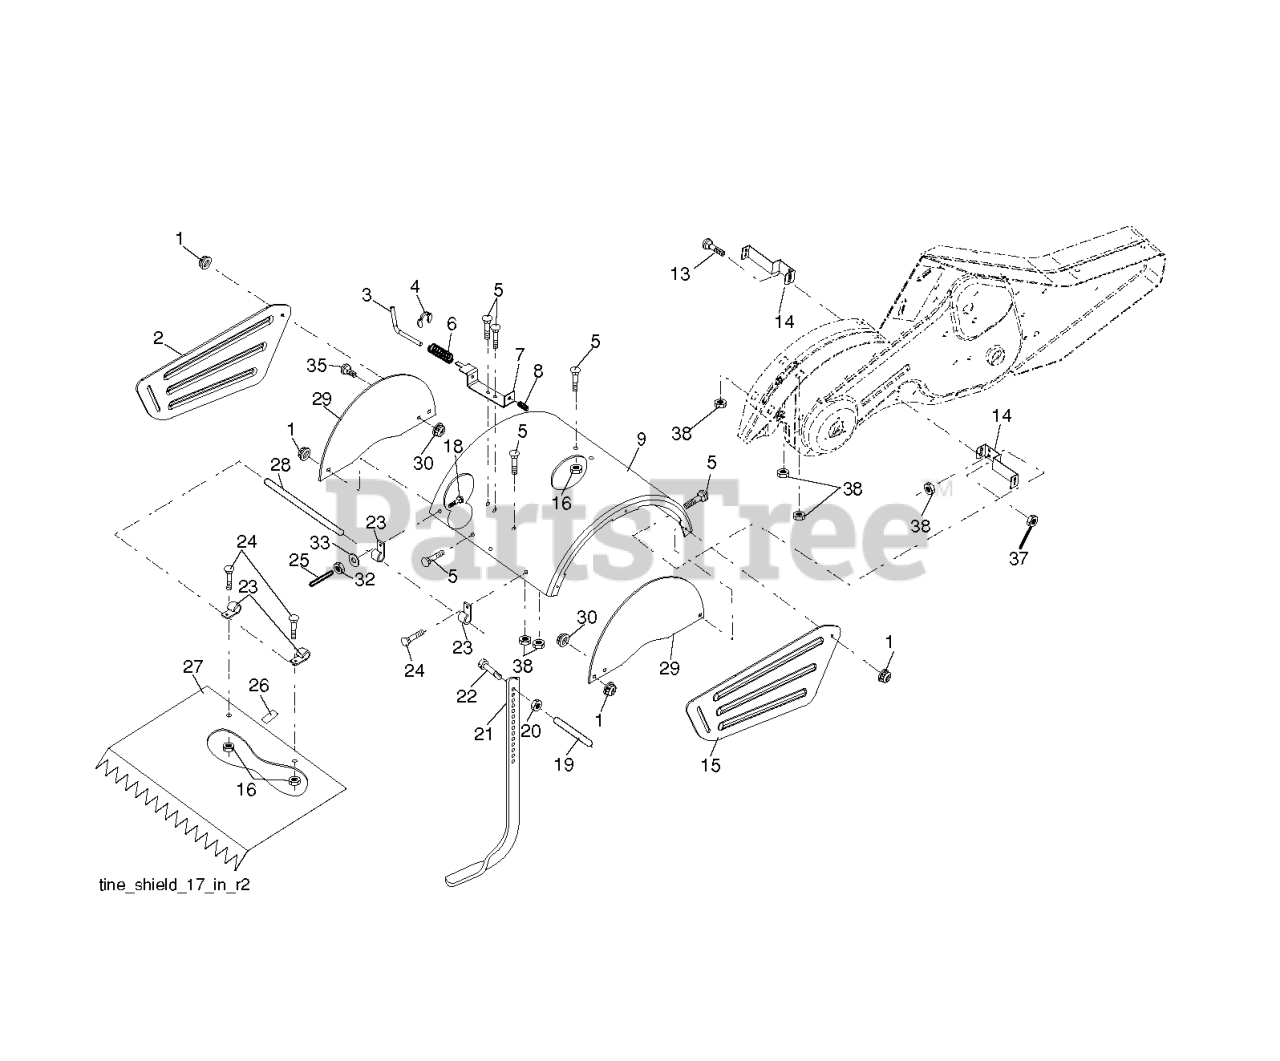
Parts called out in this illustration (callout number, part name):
1	NUT LOCK HEX FLANGE 5/16-18
2	SHIELD
3	STAKE PIN TI
4	RING, KLIP
5	BOLT, RDHD SQNK 5/16-18 X 3/4
7	BRACKET.LATCH.STAKE.3.20.BLACK
8	SPRING CRT
9	SHIELD
13	BOLT.CARRIAGE.5/16-18
14	BRACKET.TINE.SHIELD.TILLER.BLA
15	SIDE SHIELD RH
16	NUT T
20	NUT.HEX.3/8-16UNC
21	STAKE.DEPTH.16.CRT.BLACK
22	BOLT.375-16
25	VINYL CAP TI
26	PAD IDLER TI
27	SHIELD LEVELING
28	PIN.HINGE.TILLER
29	SHIELD.ASM.SIDE.ORANGE.(OLD)
30	LOCKNUT-FLANGE 5/16-18
32	NUT
33	LOCKWASHER
35	BOLT.CARR.5/16-18X5/8.SHORT
37	NUT.71038.31-18.HEX.NYLOCK
38	NUT
